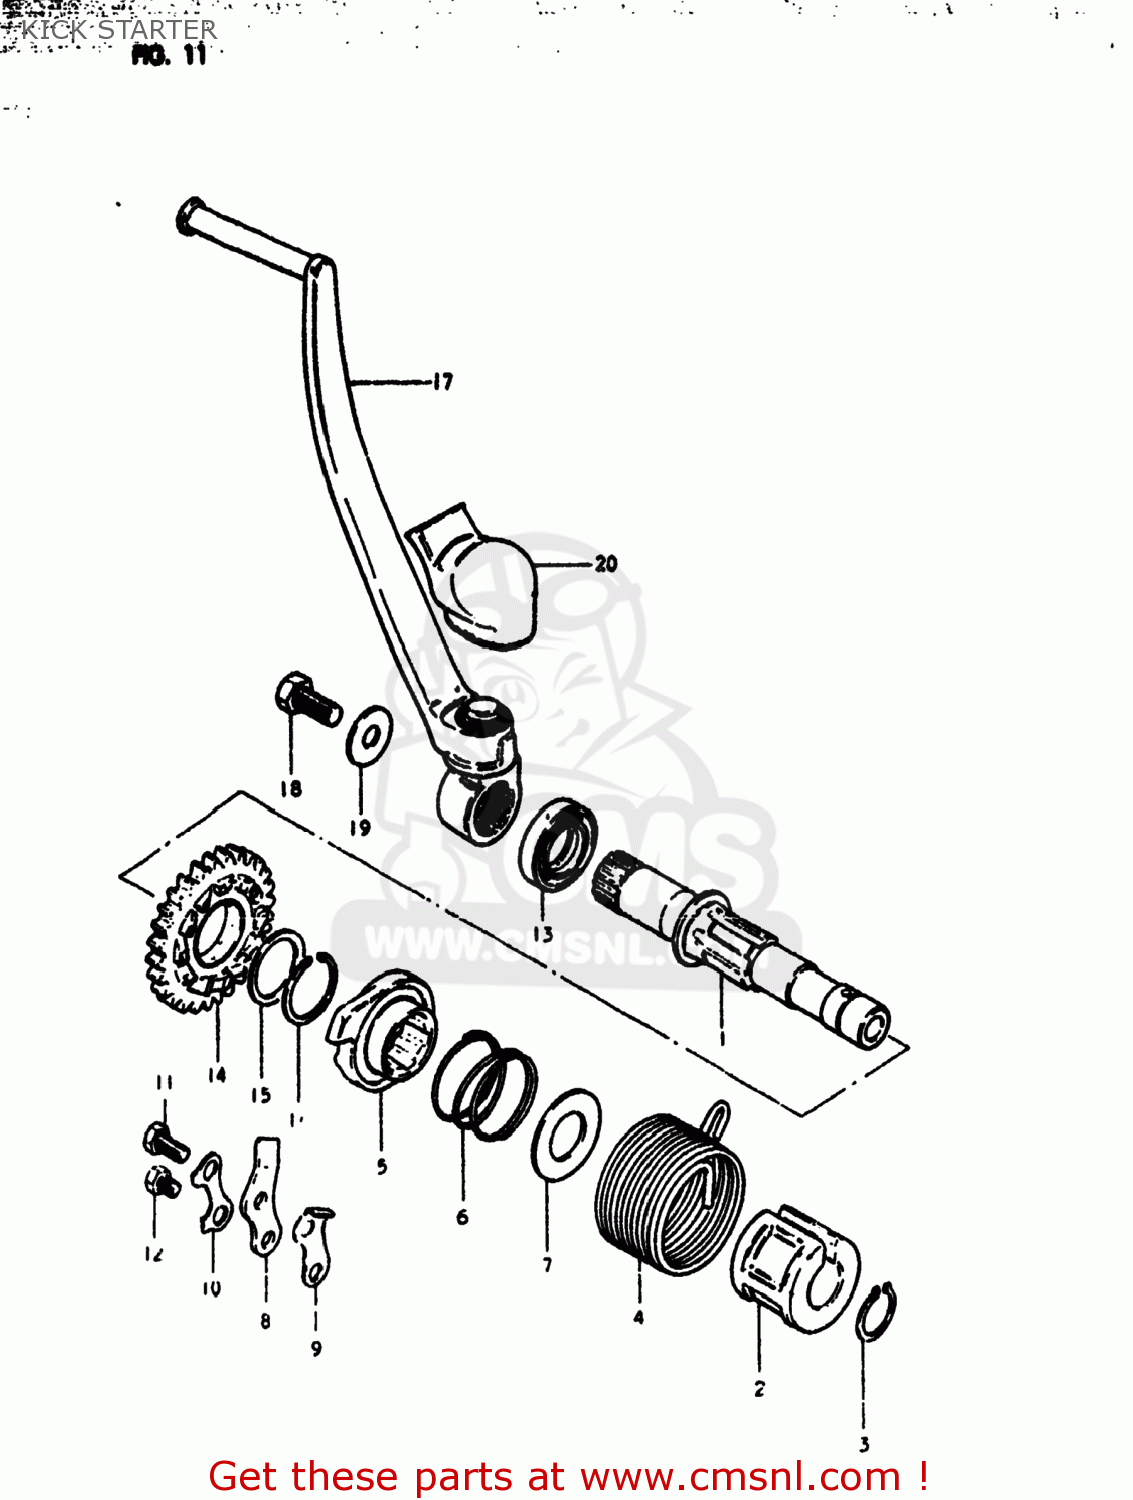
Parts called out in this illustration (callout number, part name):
1	SHAFT,KICK STARTER
2	GUIDE,KICK STARTER SFT SPRING
3	CIRCLIP
4	SPRING
5	STARTER,KICK
6	SPRING
7	WASHER
8	GUIDE,KICK STARTER
9	STOPPER,KICK STARTER
10	WASHER
11	BOLT, UPPER
12	BOLT
13	BEARING
14	GEAR,KICK STARTER DRIVE
15	SHIM
16	CIRCLIP
17	LEVER ASSEMBLY,KICK STARTER
18	BOLT
19	WASHER(8.2X23X3.2)
20	COVER,KICK LEVER JOINT
